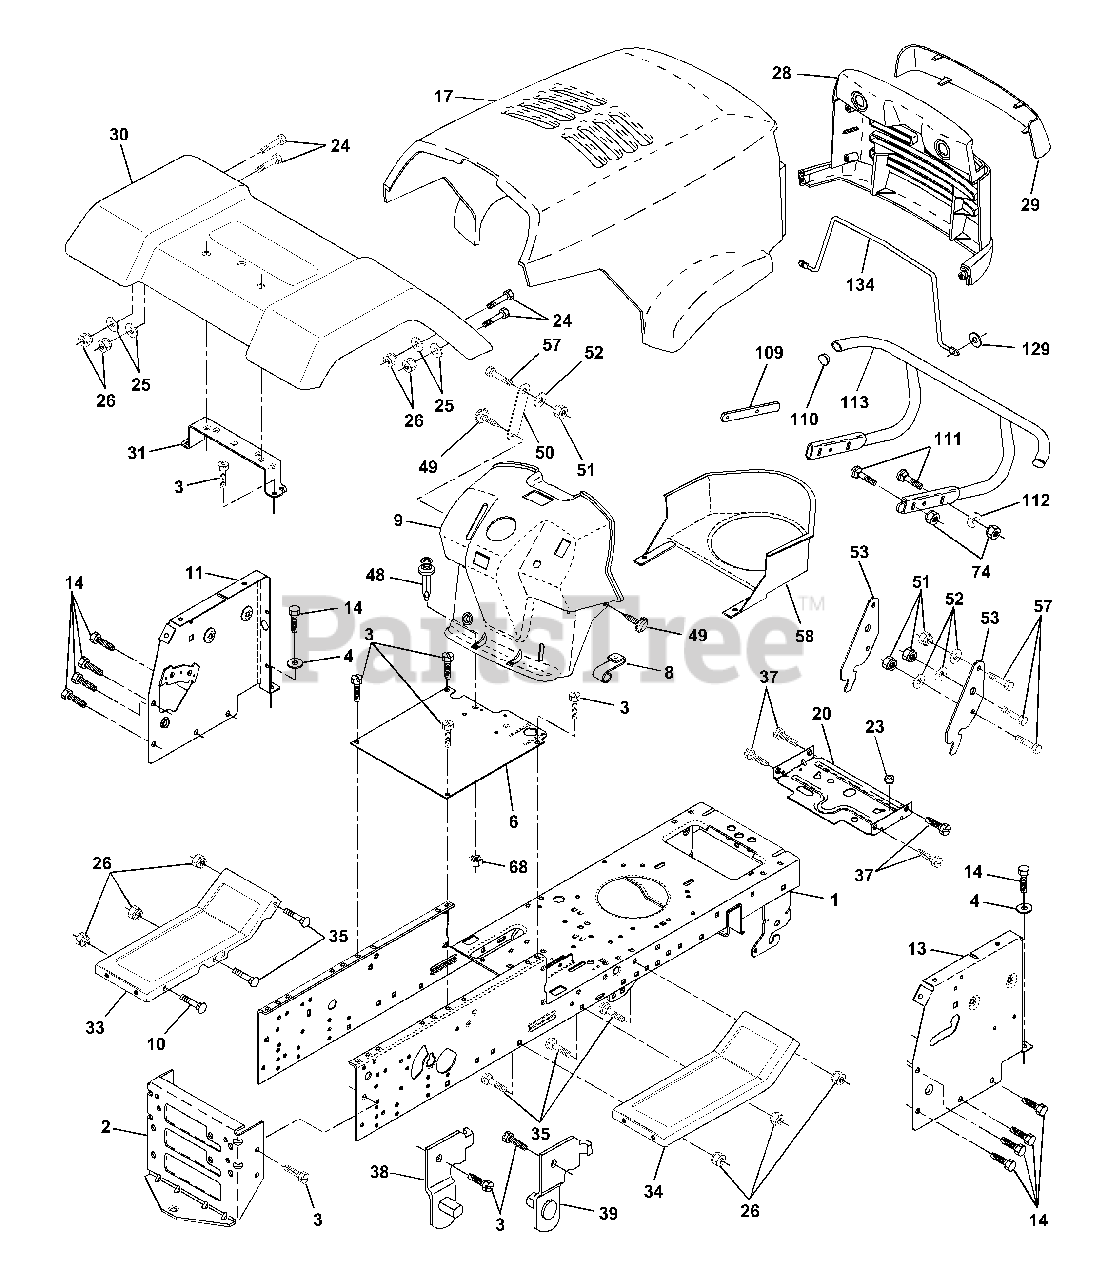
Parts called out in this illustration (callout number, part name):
1	Chassis Weldment 11 ga
2	Drawbar, Stretch
3	Screw Thdrol 3/8-16x3/4 Ty-tt
4	Washer 13/32 x 3/4 x 16 Ga.
6	Saddle LT Fender Shift
8	Clip Insulator.406 Mtg Hole
9	Dash P/L N/Amm. N/HM w/PTO Grey
10	Bolt Carriage 3/8-16 x 1
11	Panel Pnt Dash Lh
13	Panel Dash Rh
14	Screw Thdrol 3/8-16x1/2 Ty-tt
17	Hood LT/PL Husqvarna
20	Plate Mtg. Battery Fuel Tank. 95
24	Bolt Fin Hex 3/8-16unc X 1 Gr. 5
25	Washer 13/32 X 13/16 X 12 Ga
26	Nut Lock Hex W/Ins 3/8-16 Unc
28	Grille LT/PL Husqvarna
29	Lens LT/PL Husqvarna
30	Fender Pnt
31	Bracket Pnt Fender
33	Footrest Pnt Lh
34	Footrest Pnt Rh
35	Bolt Rdhd Sht Sqnk 3/8-16 X3/4
37	Screw Thdrol 5/16-18X1/2
38	Bracket, Asm. Pivot, L.H., Mower Rear
39	Bracket, Asm. Pivot, R.H., Mower Rear
48	Rivet Push Plate D Plastick Blk
49	Screw Hexwsh. Thdrol 1/4-20 x 3/4
51	Nut Lock Hex W/Ins 1/4-20
52	Washer 9/32 x 7/8 x 16 Ga.
53	Bracket Pnt. Pick off LT/PL Husq.
57	Bolt Hex 1/4-20 x 3/4
58	Air Duct P/L
68	Nut Keps Hex 1/4-20
74	Nut Crownlock 3/8-16 UNC
109	Bracket Extension Bumper
110	Plug Plastic
111	Bolt Carriage 3/8-16 x 1-1/4
112	Washer 13/32 x 13/16 x 16 Ga.
113	Bumper Asm.
129	Washer 9/32 x 5/8 x 16 Ga.
134	Rod Support Hood LT/PL Husq.
